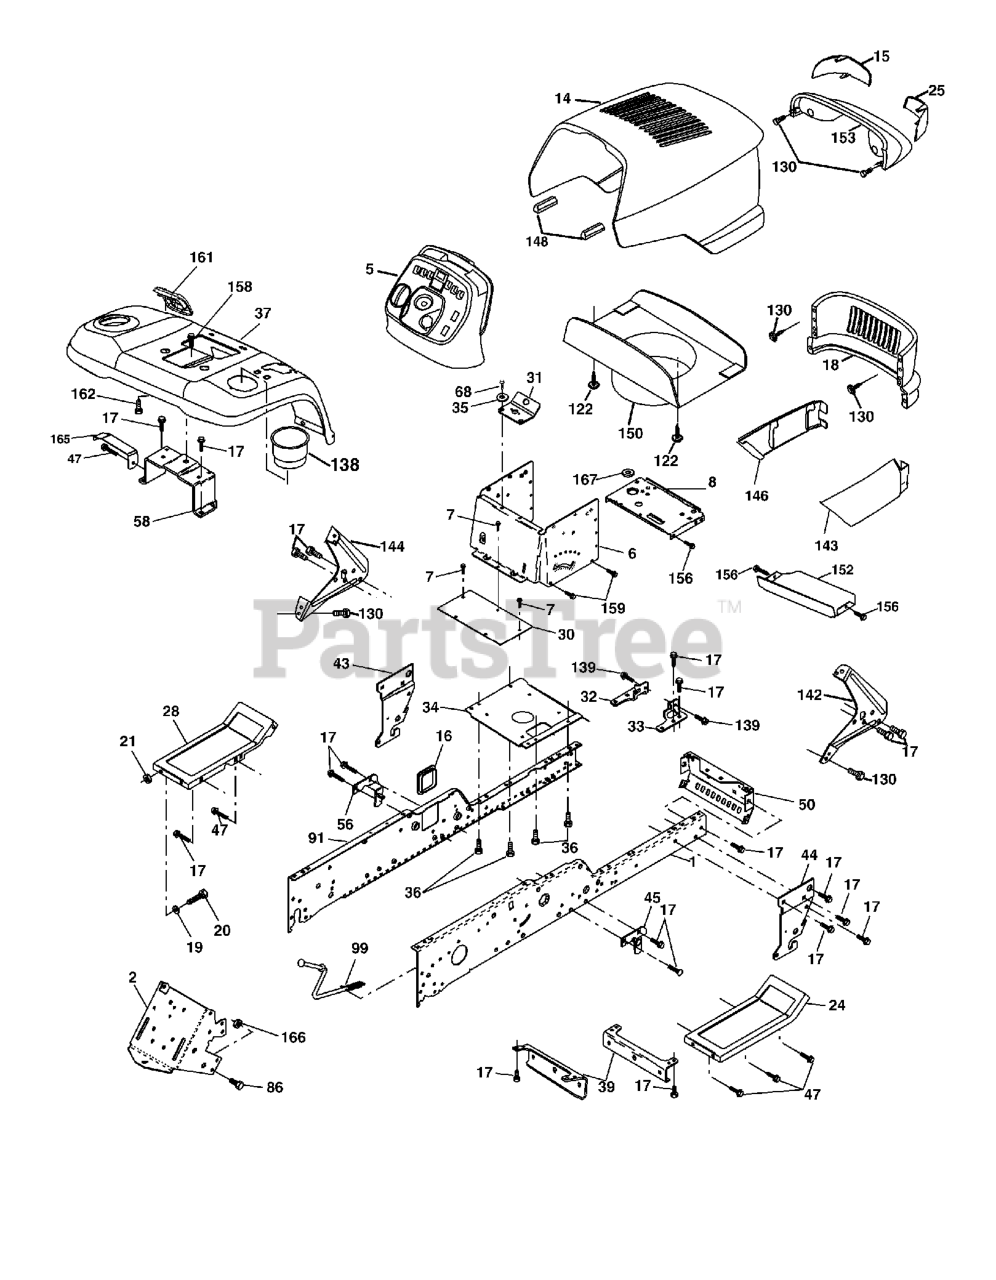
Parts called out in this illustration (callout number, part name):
1	KIT.RAIL.CHASS.RH.GT
2	DRAWBAR, GT
5	DASH
6	DASH VGT, LOWER
7	SCREW
8	SUPPORT, BATTERY
14	HOOD
15	LENS LH
16	COVER ACCESS
17	SCREW, 3/8-16X3/4
18	GRILLE.STEALTH P/L.YTGT.GREY
19	WASHER
20	BOLT
21	NUT
24	FOOTREST PNT RH
25	LENS RH
28	FOOTREST PNT LH
30	SADDLE.HYDRO.95
31	BRACKET SUPT 1-PC VGT STEERING
32	BRACKET
33	BRACKET.
34	PLATE ASM ENG CHASSIS
35	WASHER
36	SCREW 5/16"
37	FENDER, PNT
39	BRACKET AXLE, FRONT
43	FRONT SUSPENSION BRKT LH
44	FRONT SUSPENSION BRKT RH
45	BRACKET, ASM., SUSP CHASSIS RH
47	SCREW LT
50	BRACKET, CHASSIS FRONT
56	BRACKET ASM., SUSP CHASSIS LH
58	BRACKET ASM., FENDER
68	Screw 5/16-18 x 1/2 Hex, Self Tapping 5/16-18 x 1/2
86	BOLT FIN HEX 7/16-14 X 1
91	KIT.RAIL.CHASS.LH.GT
99	ROD ASM, BYPASS
122	SCREW.HEX.WS.HD.8-18 X 7/8
130	SCREW
138	CUPHOLDER
139	BOLT, SHOULDER 5/16-18
142	BRACKET DASH STEALTH(R)
143	SKIRT GRILLE RH
144	BRACKET DASH STEALTH LH
146	SKIRT GRILLE LH
148	EXTRUSION BUMPER (3 2) (2 2)
150	DUCT.HEAT.HOOD.STEALTH.GT
152	BROWNING SHIELD
153	LIGHTBOX.ASM.STV.DL.INC.HUSQ
156	SCREW
158	SCREW 3/8-16X1/2
159	SCREW, 3/8-16X3/4
161	CONSOL.FUEL.WINDOW.BLACK
162	SCREW.HI-LO.CONSOLE
165	BRACKET SUPPORT TANK
166	Nut, Crownlock Hex 7/16-14 unc
167	BUSHING SNAP
